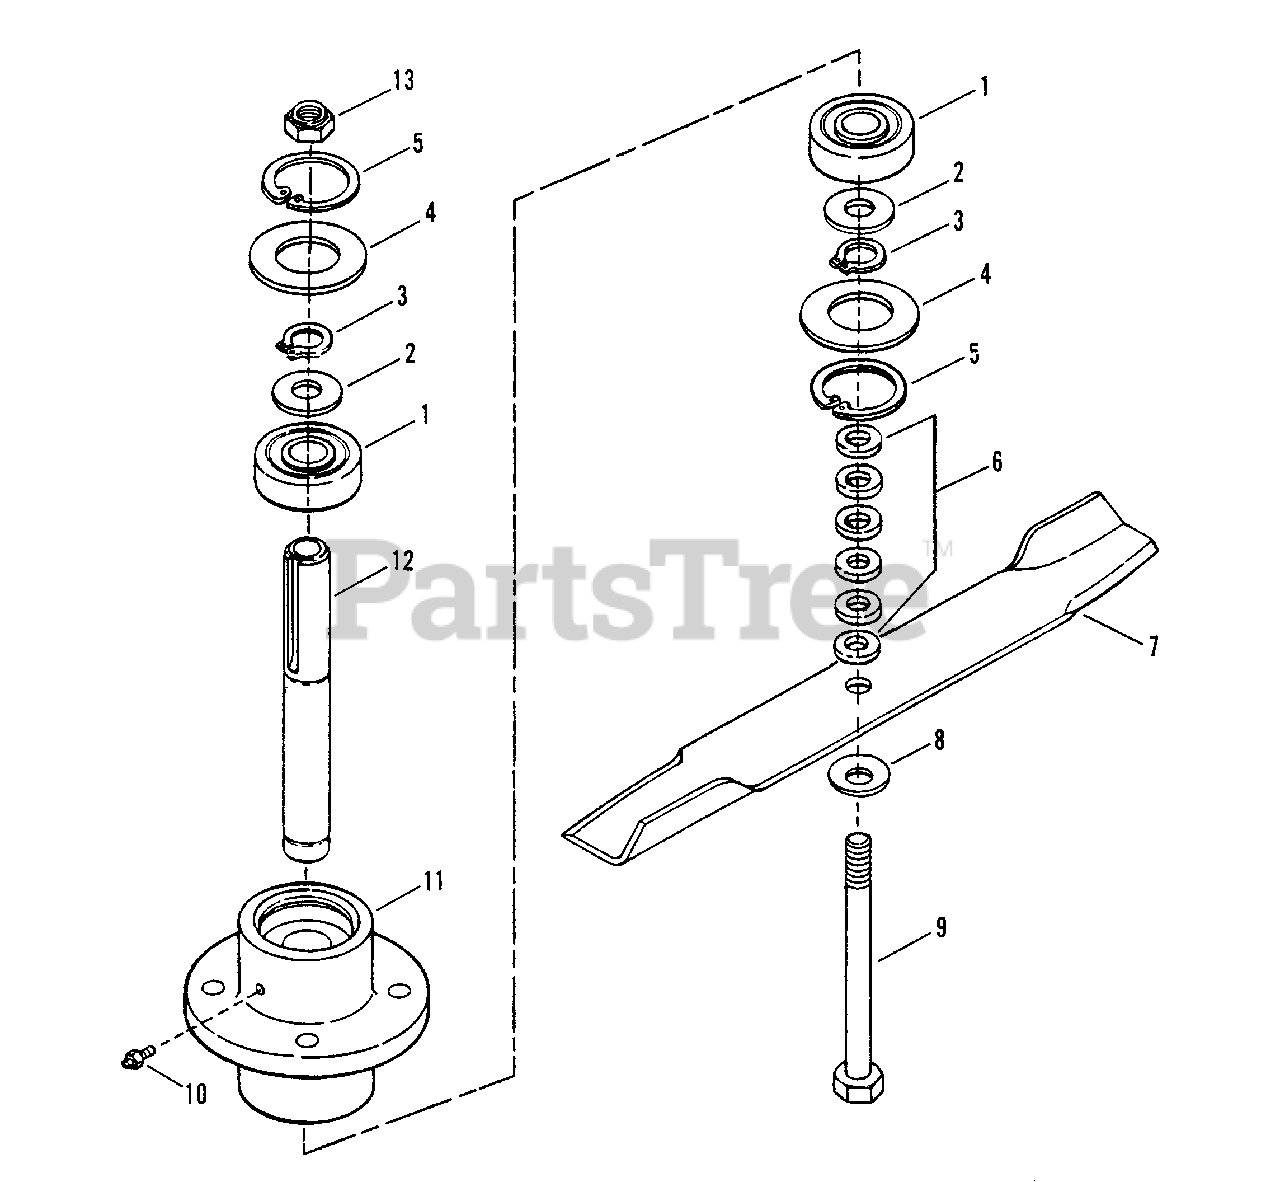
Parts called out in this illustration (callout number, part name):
1	Bearing, Sealed
2	Washer, Spindle
3	Snap-Ring, Spindle
4	Washer, Spindle Housing
5	Snap-Ring, Spindle Housing
6	Spacer, Blade
7	Blade, 18" (36")
8	Washer, Beveled
9	Bolt, 5/8-18 x 9-3/4 Hex Head Cap, Grade 5
10	Fitting, Lube
11	Housing, Cutter
12	Shaft, Spindle
13	Nut, 5/8-18 Hex
